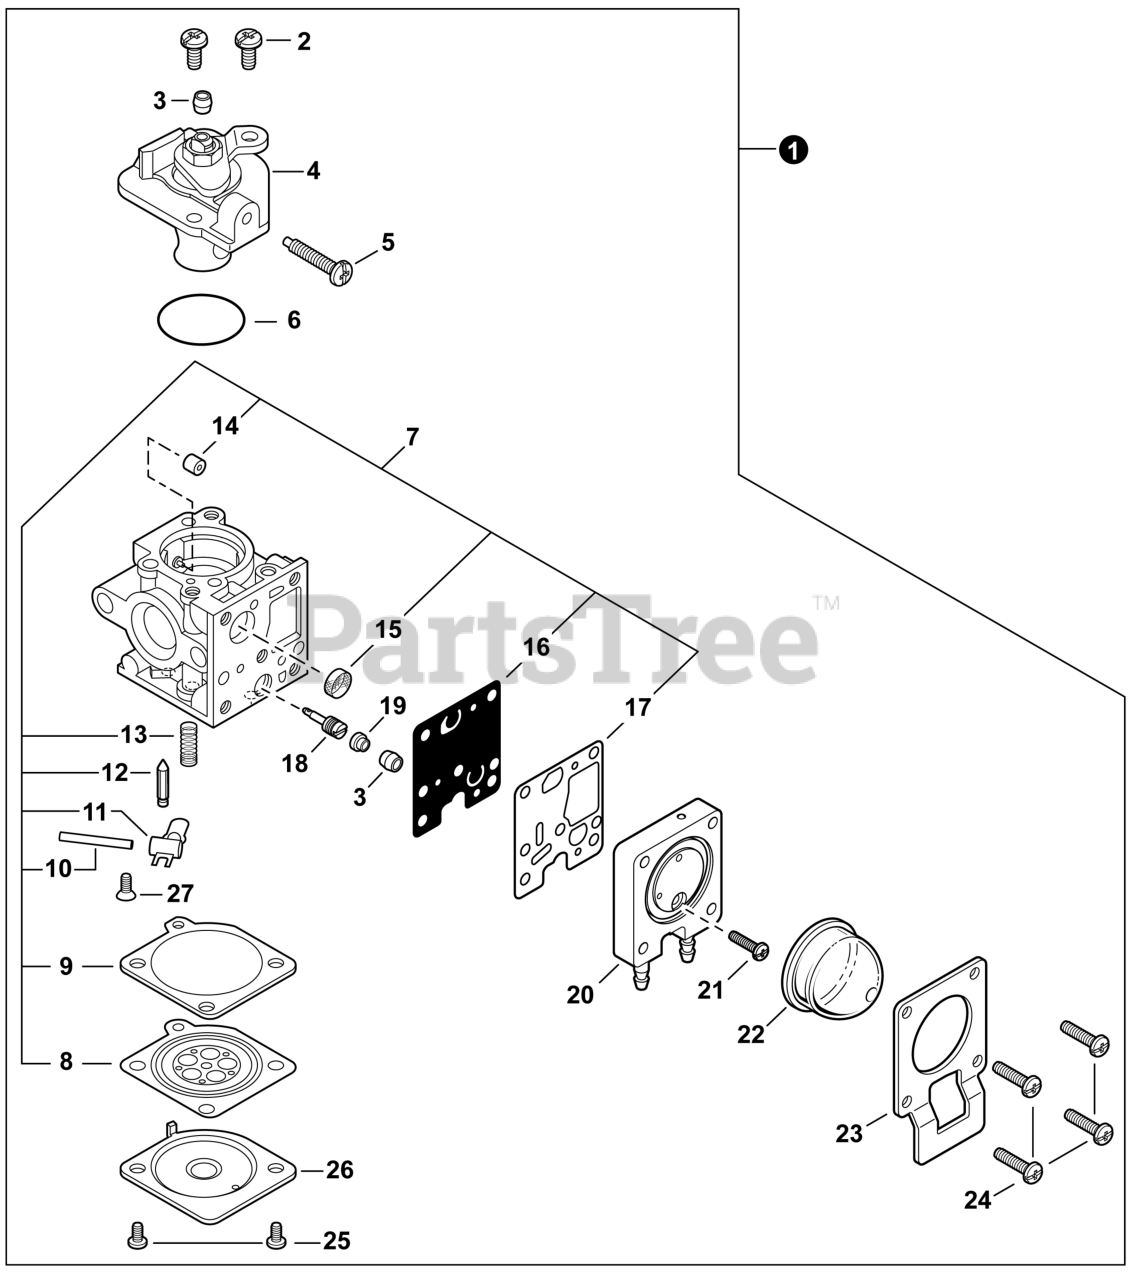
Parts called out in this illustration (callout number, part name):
1	CARBURETOR - Z011/37C
4	COVER ASSY, ROTOR
7	REPAIR KIT, CARBURETOR
8	DIAPHRAGM, METERING
9	GASKET, METERING DIAPHRAGM
10	PIN, METERING LEVER
11	LEVER, METERING
12	VALVE, INLET NEEDLE
13	SPRING, METERING LEVER
14	GUIDE, ROLLER
15	SCREEN, FUEL INLET
16	DIAPHRAGM, PUMP
17	GASKET, PUMP
18	NEEDLE, MIXTURE
19	CAP, LIMITER
20	BODY ASSY, PURGE
22	BULB, PURGE
23	RETAINER, PURGE BULB
26	COVER, METERING DIAPHRAGM
